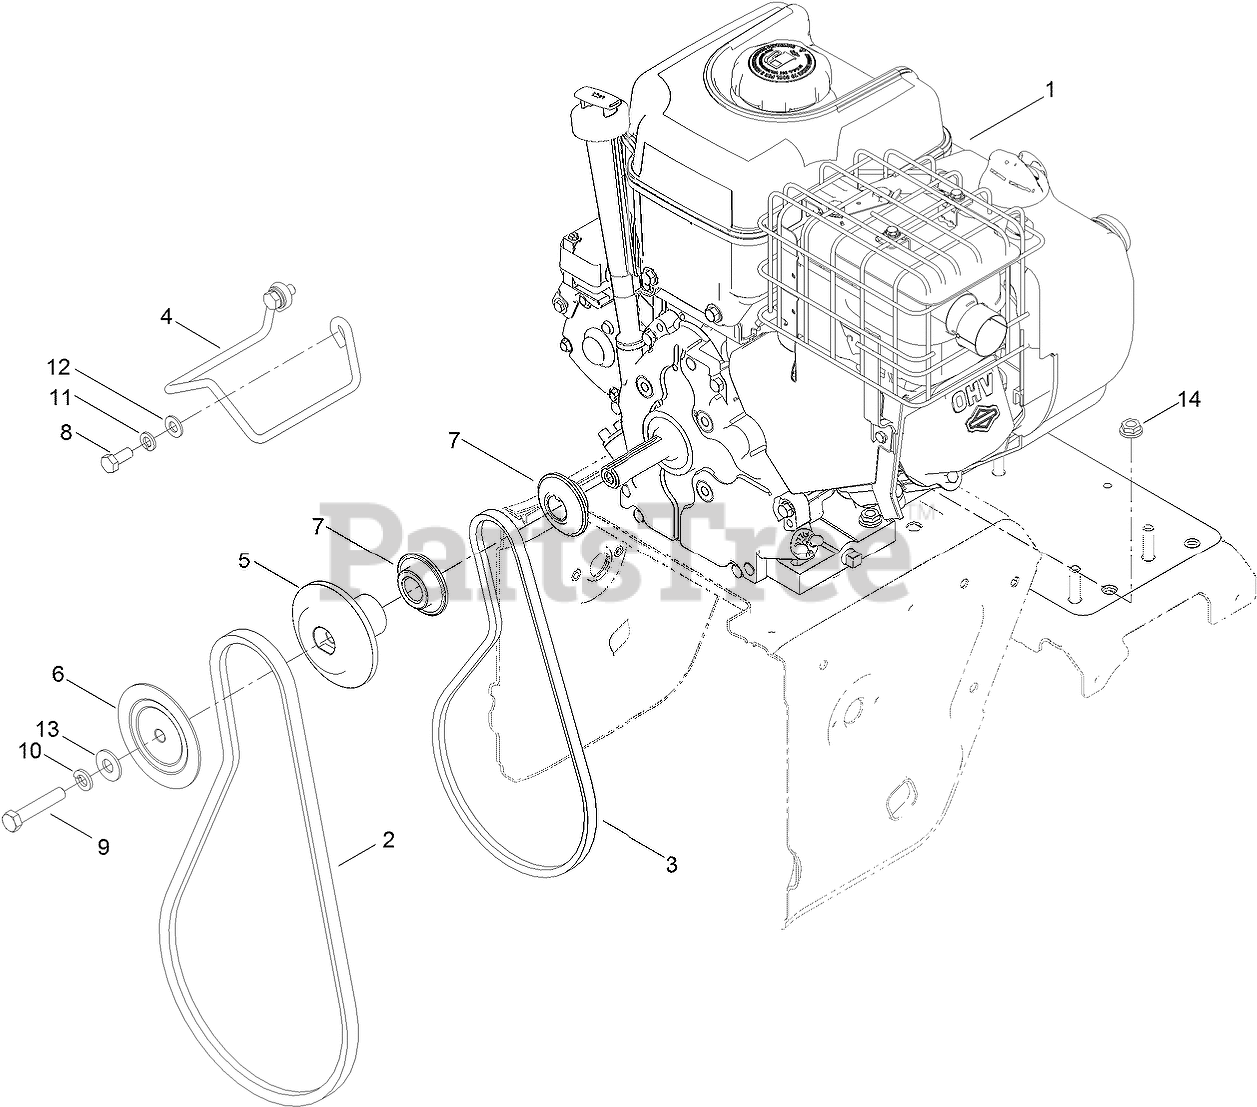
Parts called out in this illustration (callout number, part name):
2	BELT-V
3	BELT-V
4	GUIDE-BELT
5	PULLEY-AUGER, REAR
6	PULLEY-AUGER, FRONT
7	PULLEY-TRACTION
8	SCREW-HH
9	SCREW-HH
10	WASHER-LOCK
11	WASHER-LOCK
12	WASHER-PLAIN
13	WASHER-FLAT
14	NUT-HF
